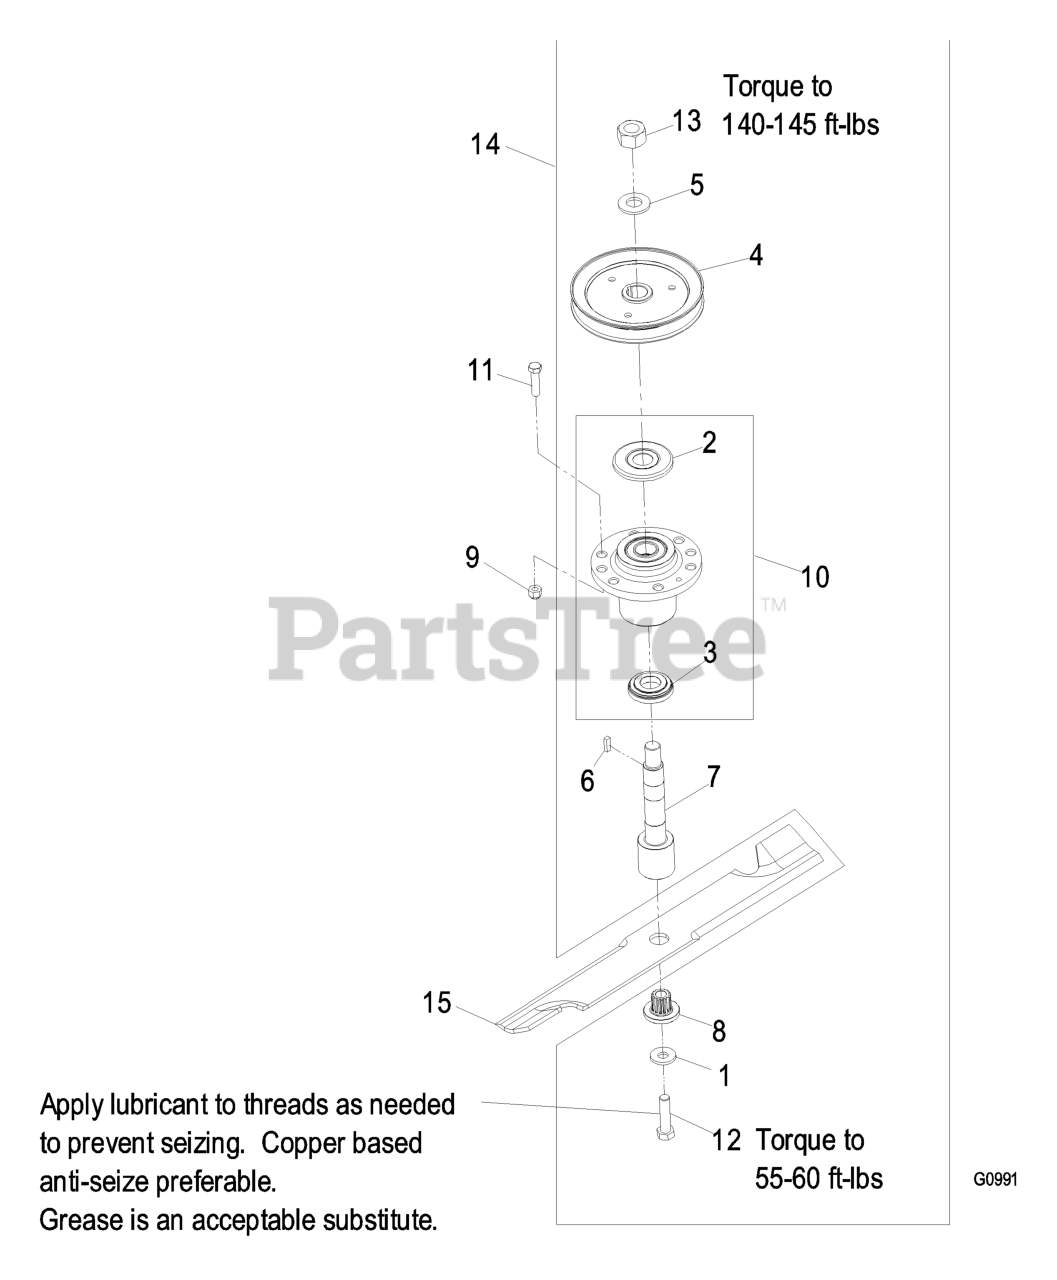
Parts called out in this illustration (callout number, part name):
1	WASHER-SPRING
2	GUARD-BEARING, TOP
3	SPACER-GUARD, BOTTOM
4	SHEAVE,BLADE DRIVE 6.30
7	KIT, SPLINED SPINDLE 103-
8	BUSHING,SPLINED
9	NUT-LOCK, NI
10	KIT, CUTTER HOUSING
11	SCREW-HH
12	SCREW-HH
13	NUT-HH
14	ASM, CUTTER HSG COMPLETE
